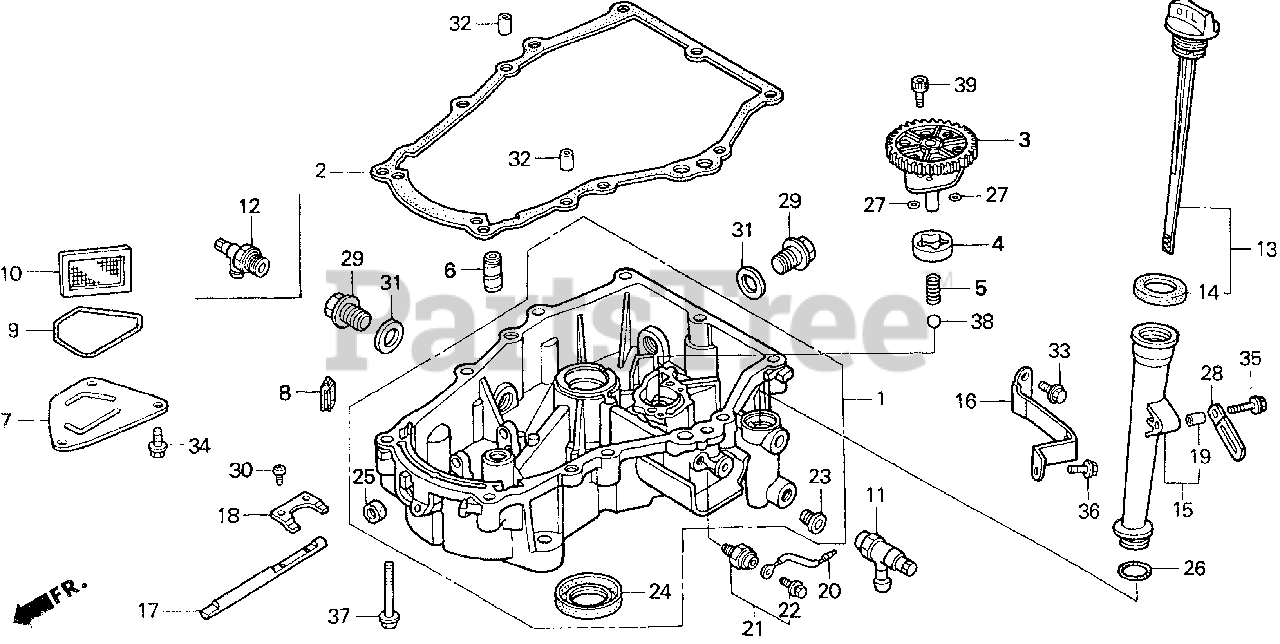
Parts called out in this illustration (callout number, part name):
1	PAN ASSY., OIL
2	GASKET, CASE COVER
3	COVER ASSY., OIL PUMP (TWO BOLTS)
4	ROTOR, OIL PUMP (OUTER)
5	SPRING, RELIEF VALVE
6	SHAFT, OIL CONTROL
7	PLATE, OIL FILTER
8	RUBBER, OIL RETURN
9	O-RING, OIL PLATE
10	SCREEN, OIL FILTER
11	VALVE, DRAIN (14X1.5)
12	VALVE, OIL SHUT-OFF
13	CAP ASSY., OIL FILLER
14	GASKET, OIL FILLER CAP
15	EXTENSION, OIL FILLER
16	STAY, OIL FILLER EXTENSION
17	SHAFT, GOVERNOR ARM
18	FORK, GOVERNOR
19	COLLAR, EXTENSION
20	WIRE, OIL PRESSURE SWITCH
21	SWITCH, OIL PRESSURE
22	SCREW-WASHER (4X8)
23	BOLT, SEALING
24	OIL SEAL (38X58X11)
25	OIL SEAL (10X20X5)
26	O-RING (22.5X2.2)
27	O-RING (13X3.0)
28	CLIP, CABLE
29	BOLT, DRAIN PLUG (20MM)
30	SCREW, PAN (5X10)
31	WASHER, DRAIN PLUG (20MM)
32	PIN A, DOWEL (8X14)
33	BOLT, FLANGE (6X12)
34	BOLT, FLANGE (6X14)
35	BOLT, FLANGE (6X28)
36	BOLT, FLANGE (8X16)
37	BOLT, FLANGE (8X50)
38	BALL, STEEL (#12) (3/8)
39	BOLT, SOCKET (6X16)
